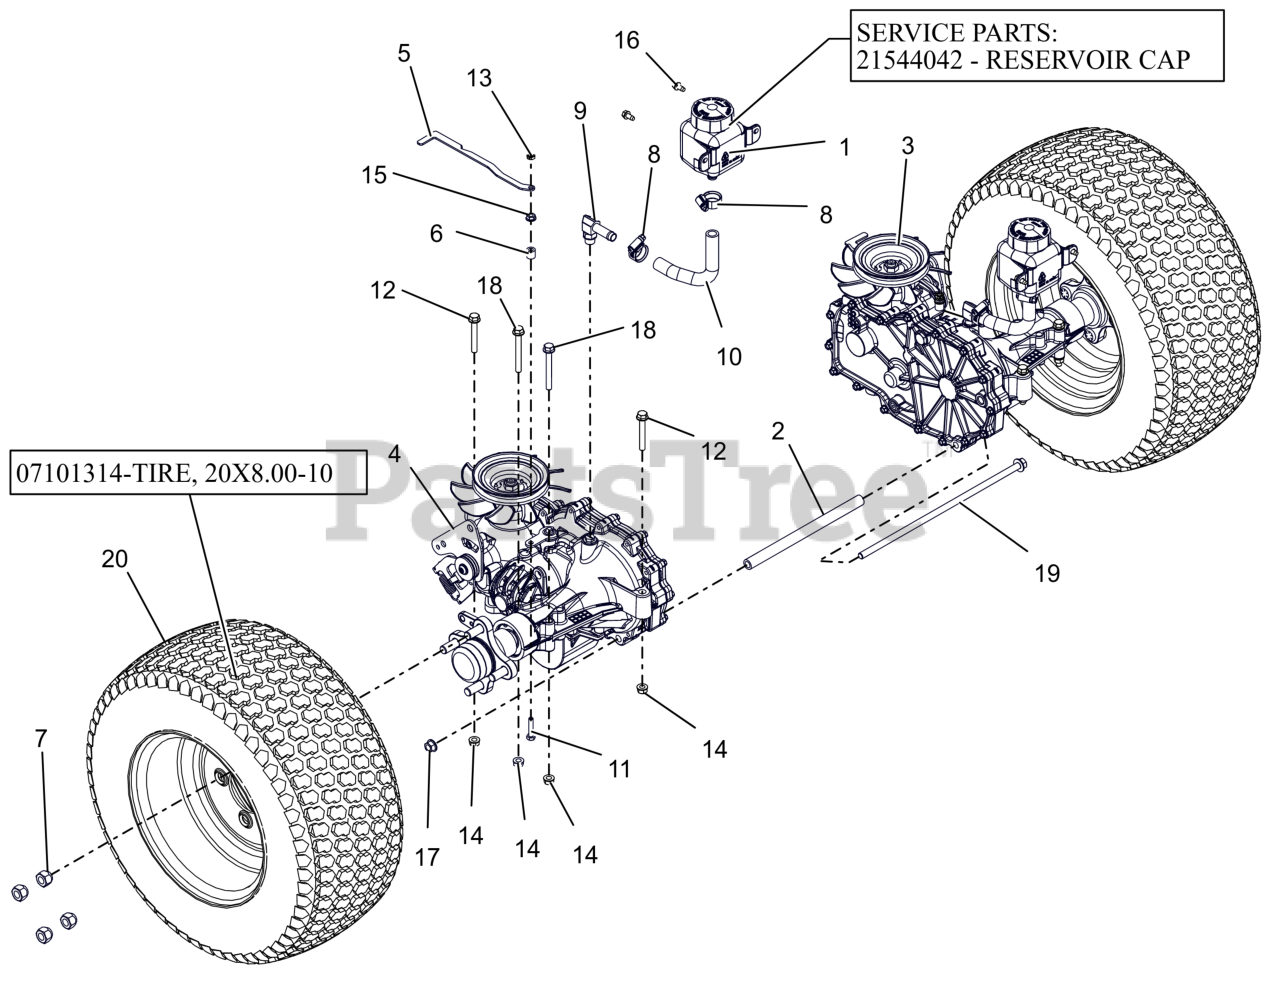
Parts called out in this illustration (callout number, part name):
1	TANK, EXPANSION
1	CAP, HYDRO RESERVOIR REPLAC.
2	TUBE, TRANSAXLE BRACE -9.27LG
3	TRANSAXLE,ZT2800 LH
4	TRANSAXLE,ZT2800 RH
5	BRKT, DUMP VALVE
6	BSHG-SLV .265X.500X.500
7	NUT, WHEEL .50-20 ZCC
8	CLAMP,.88 DIA. HOSE
9	FITTING, HYD (90 DEG)
10	HOSE, FORMED LH XL
11	BLT, HEX .25-20X1.25 G5 ZCC
12	BLT,HEX-FLG .31-18X2.25 G5 ZCC
13	NUT-LK-CTR JAM .25-20 YWZC
14	NUT,LK-CTR-FLG .31-18 GF ZCC
15	NUT-SPNLK-FLG .25-20 ZC120
16	SCR-TAP .25-20X.50 HWH ZCC
17	NUT-LK-CTR-FLG .375-16 GF ZCC
18	BLT,HEX-FLG .31-18X2.75 G5 ZCC
19	BLT,HEX-FLG .38-16X13 G5 ZCC
20	ASM, WHL/TIRE 20X8.00-10
20	TIRE, 20X8.00-10 (MONITOR)
20	TUBE, 20X10-10
